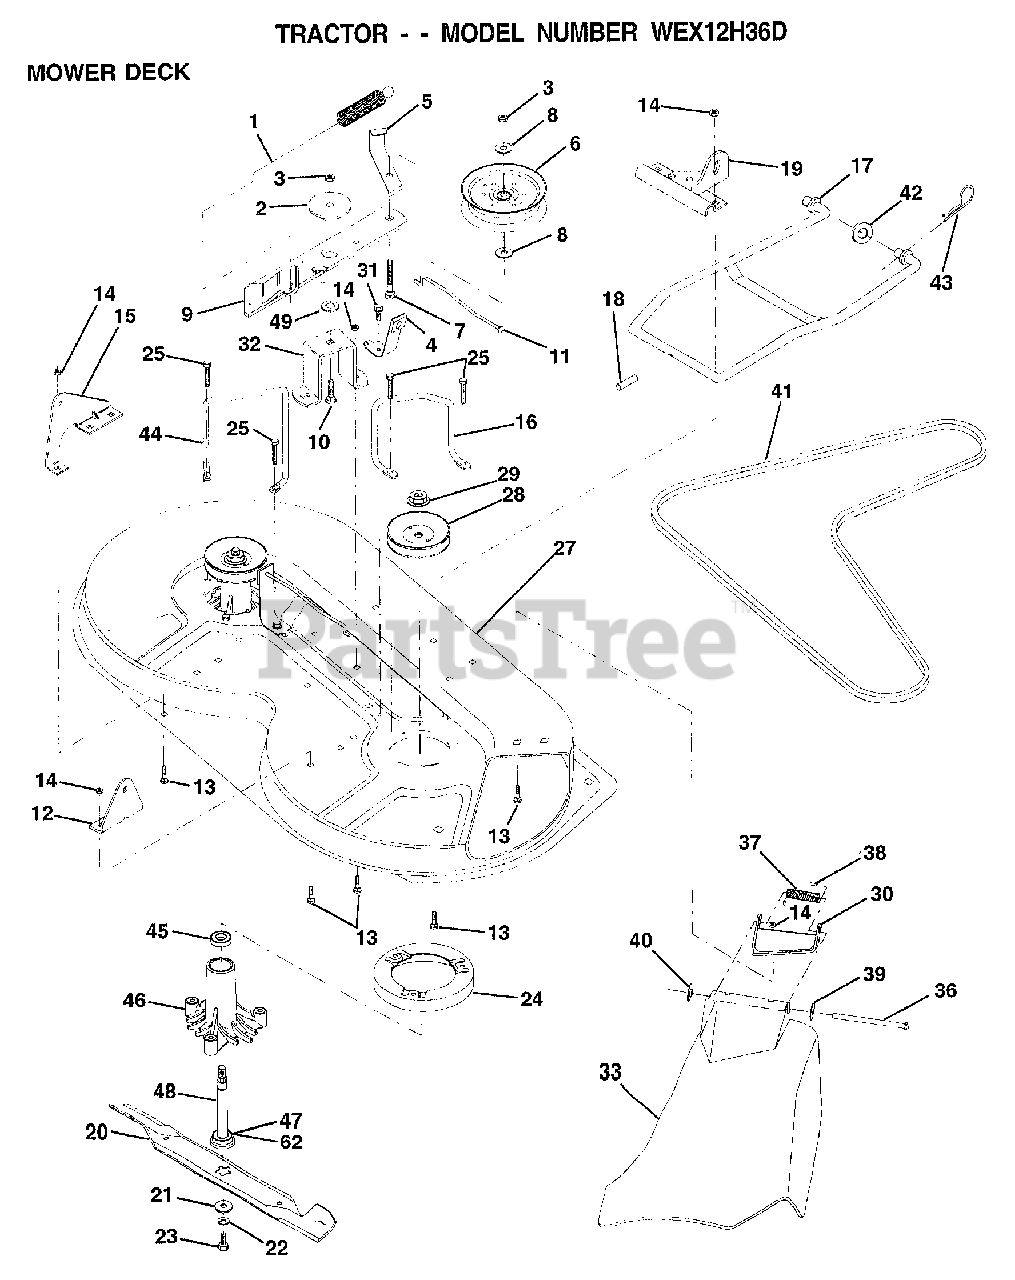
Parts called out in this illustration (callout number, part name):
1	SPRING CLUTCH MWR
2	SPACER.RETAINER.MOWER
4	BRAKE ASM
5	IDLER BELT GUIDE
6	PULLEY IDLER
7	BOLT
8	WASHER
10	BOLT.3/8-14X1.25
11	BRAKE ROD
12	"BRKT,LIFT REAR"
13	BOLT
15	"BRKT,LIFT REAR LH"
16	"KEEPER-BELT,RH"
17	MOWER LINK STAB
18	"PIN,GROOVE"
19	"BRKT,LINK STABILI"
20	"BLADE.36"" HIPERF"
21	WASHER.HARD.BLADE
23	BLADE BOLT
24	STRIPPER RND MWR
25	"SCREW-THD ROLL,WA"
27	"HOUSING-MOWER,36"""
28	PULLEY.MAND.36/46
31	SCREW LT
32	"SUPT,IDLER ARM"
33	SHIELD, DEFLECTOR
36	HINGE ROD
37	SPRING TORSION
38	CAP-SLEEVE LT
39	WASHER
40	NUT PUSH M
41	V-BELT.PRIM.78.5.
43	RETAINER SPRING
44	KEEPER BELT LH
45	BEARING
46	HSG ASM MANDREL
47	BEARING.BALL
49	HARDENED WASHER
62	WASHER.FELT.
